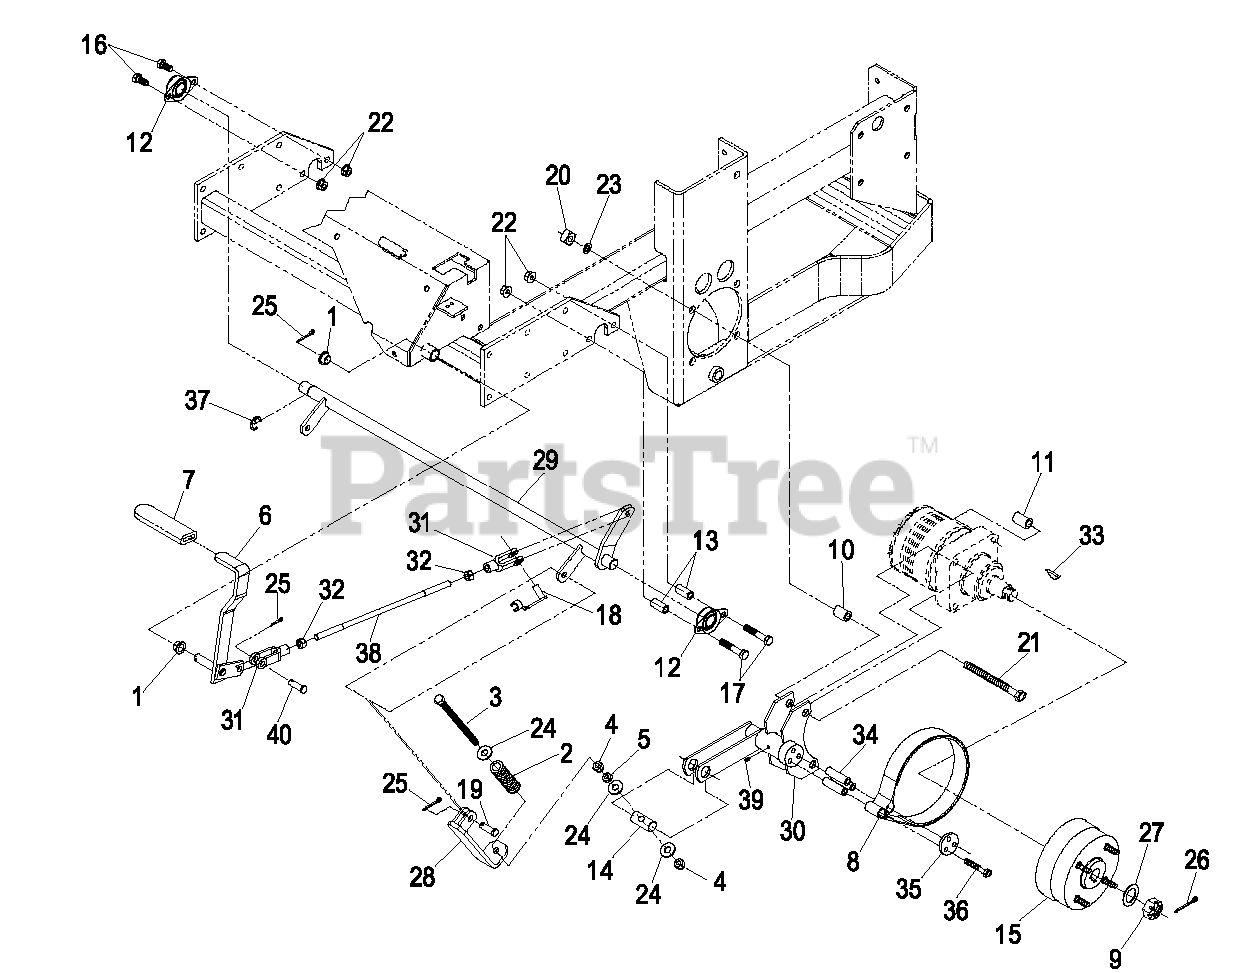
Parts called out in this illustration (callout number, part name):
1	BEARING-CONTROL
2	SPRING-BRAKE
3	BOLT-TAP, HH
4	NUT-LOCK, NI
5	NUT-JAM
6	BRAKE LEVER AND GRIP ASM
7	GRIP-LEVER
10	SPACER-WHEEL, SHORT
11	SPACER-WHEEL, LONG
12	BEARING-FLANGE, SIDE
13	SPACER-RETAINER, BRAKE
14	PIN-TRUNION
15	WHEEL HUB ASM
16	SCREW-HH
17	SCREW-HH
18	PIN-SPRING, CLEVIS
19	PIN-CLEVIS
21	SCREW-HH
22	NUT-HHF, WHIZ
23	WASHER-LOCK
24	WASHER-FLAT
25	PIN-COTTER
26	PIN-COTTER
27	WASHER-SPACER
28	LINKAGE-BRAKE, LOWER
29	SHAFT-BRAKE
30	BRAKE-WIDE
31	YOKE-LINKAGE, BRAKE
32	NUT-HEX
33	KEY-WOODRUFF
35	RETAINER-BAND, BRAKE
36	SCREW-HH
38	ROD-BRAKE
39	FITTING-GREASE
40	PIN-CLEVIS
